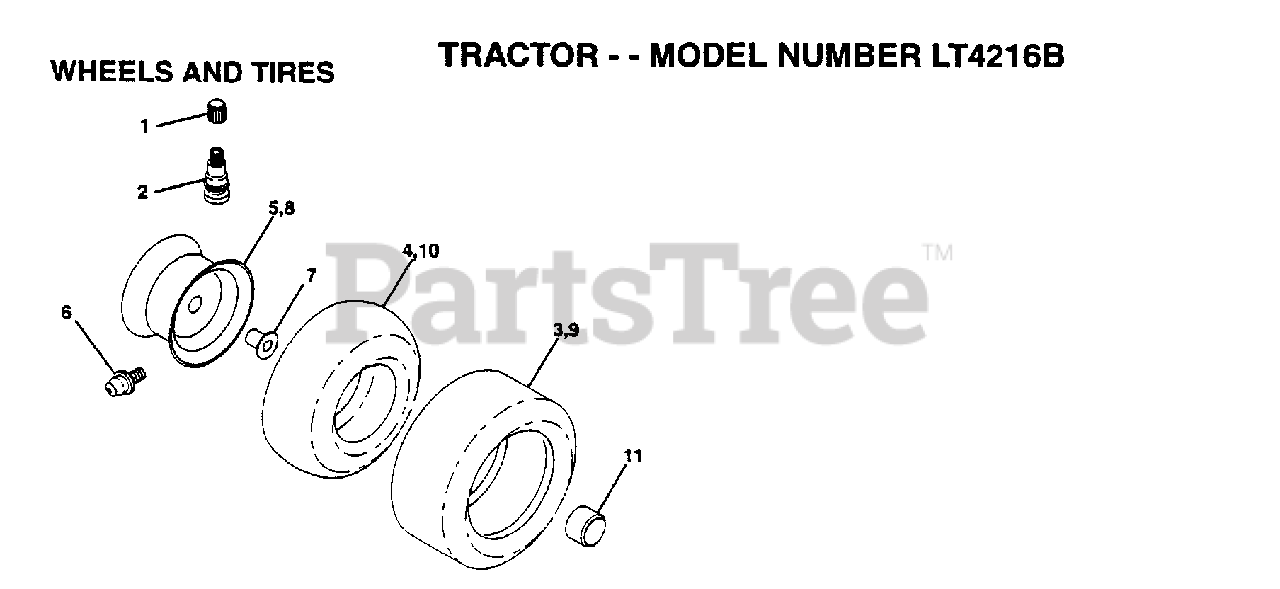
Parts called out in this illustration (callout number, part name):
1	VALVE CAP
2	VALVE STEM LT
4	TUBE.5.3/4.5/6
5	"RIM FRT 6"" ASM"
6	FITTING LT
7	"FLANGE, BEARING"
8	"RIM REAR 8"" ASM"
9	TIRE.20X8-8
10	TUBE.18X9.5-8
11	HUB CAP
